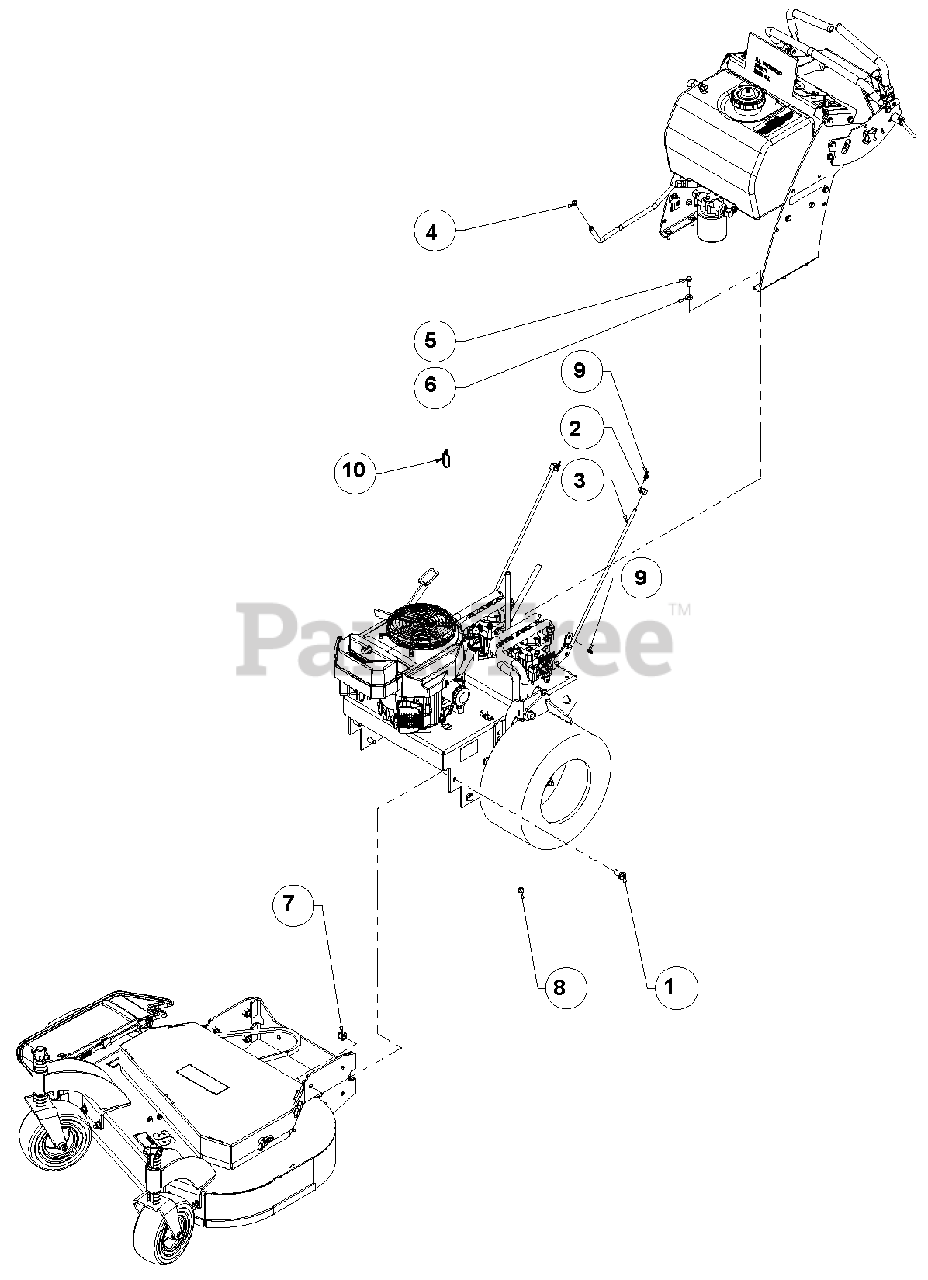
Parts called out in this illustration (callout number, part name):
1	Bolt, .50-13 x 1.25
2	Swivel, .38-24
3	Rod, Drive Control
4	Clamp, Hose - 1/2" Spring
5	Bolt, .38-16 x 1.00 Hex 5
6	Washer, .313 Reg Flat
7	Locknut, .50-13 Nyloc
8	Locknut, .38-16 Nyloc
9	Ring, Rue .375 x .054 x 1.254
10	Cable Tie, .15 x 8.50
